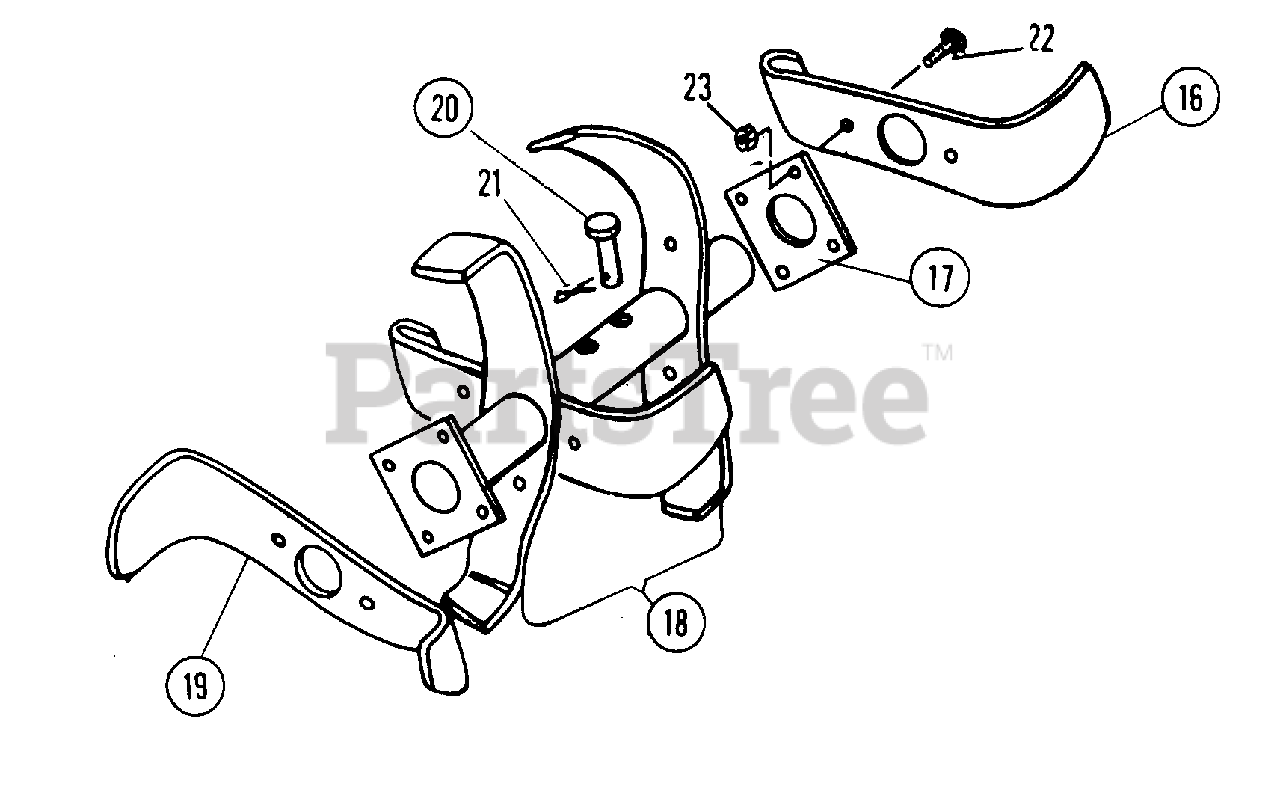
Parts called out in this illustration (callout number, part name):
16	TINE, RIGHT HAND
17	PLATE, TINE ATTACHING
18	TINE ASSEMBLY - RIGHT HAND
18	TINE ASSEMBLY - LEFT HAND
19	TINE, LEFT HAND
20	PIN, TINE SHEAR
21	PIN, 1/8 x 1 COTTER
22	BOLT, 7/16-20 x 1 HEX HEAD
23	LOCKNUT, 7/16 - 20 HEX
